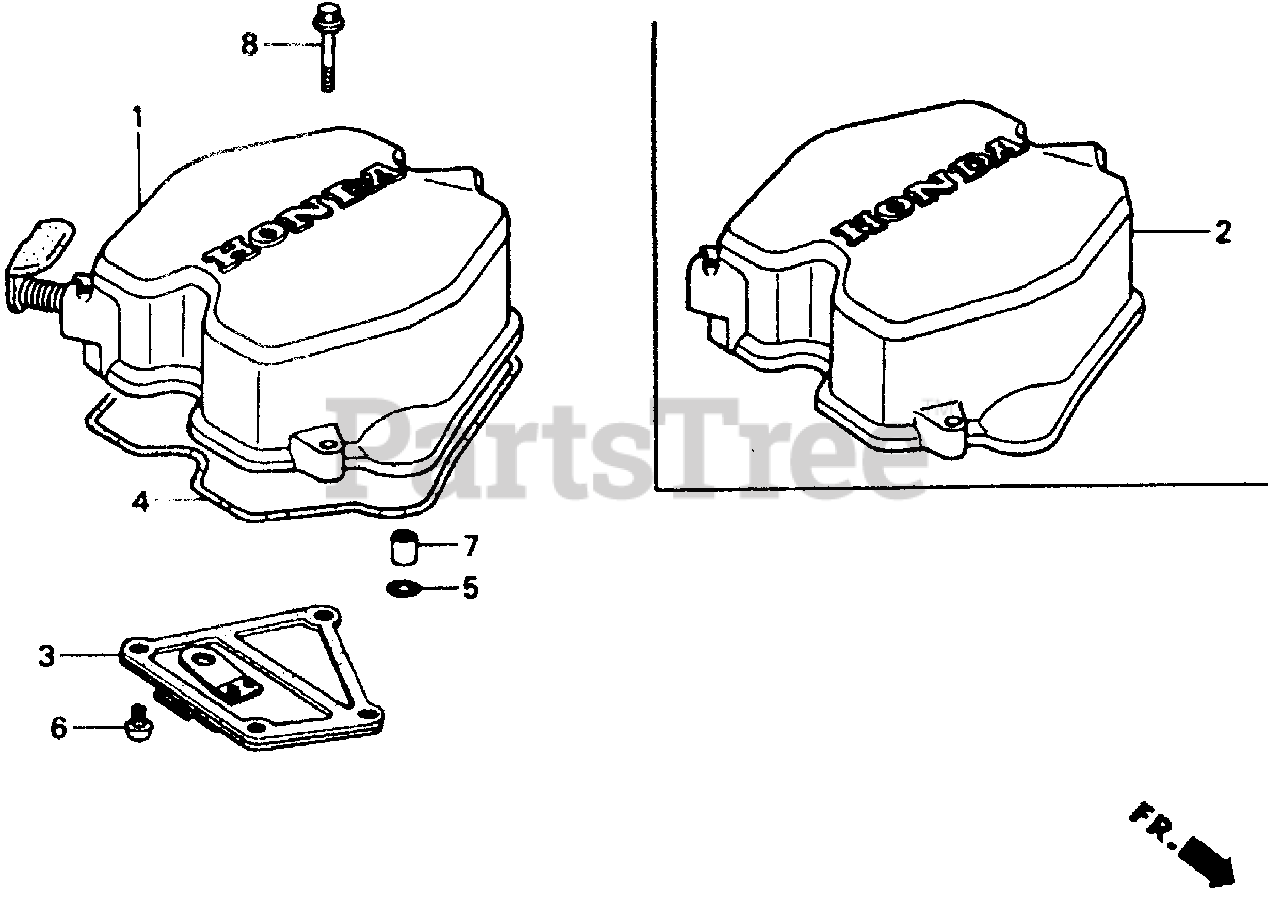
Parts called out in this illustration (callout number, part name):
2	COVER, CYLINDER HEAD
3	PLATE, BREATHER
4	O-RING, HEAD COVER
5	O-RING
6	SCREW, PAN (6X8)
7	PIN A, DOWEL (6X10)
8	BOLT, FLANGE (6X32)
